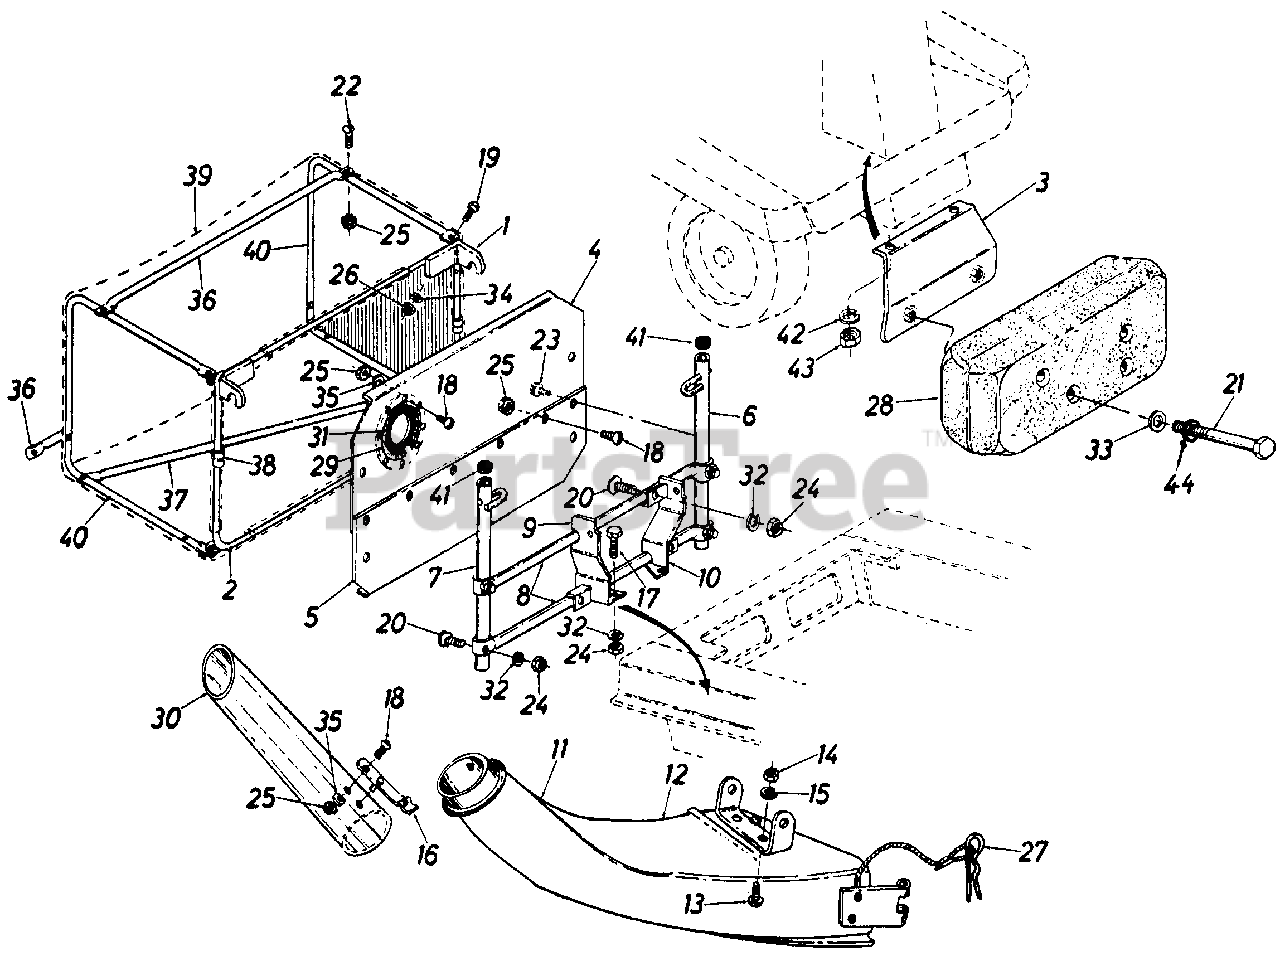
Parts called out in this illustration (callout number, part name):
1	Catcher Frame Ass'y. - Upper
2	Gatcher Frame Ass'y. - Lower
3	Counterweight Support 8racket. Ass'y.
4	Front Cover - Upper Half
5	Front Cover - Lower Half
6	L.H. Vertical Support Ass'y.
7	R.H. Vertical Support Ass'y.
8	Horizontal Support Tubing
9	Catcher Support B rkt. Ass'y.- R . H .
10	Catcher Support B rkt. Ass'y.- L. H .
11	Discharge Chute Ass'y.
12	Brkt. Chute Hinge
13	Carr. Bolt 1/4-20 x .62" Lg.
14	Hex Nut 1/4-20 Thd.*
15	L-Wash. 1/4" I.D.*
16	Spring Lock Ass'y.
17	Hex Bolt 5/16-18 x .75" Lg. *
18	Truss Mach. Scr. #10-24 x .38" Lg. *
19	Hex Bolt 1/4-20 x .62" Lg.*
20	Curved Calr. Boil 5/16-18 x 1.75" Lg.
21	Hex Bolt 3/8-16 x 4.50" Lg.*
22	Truss Mach. Scr. #10-24 x 1.0" Lg. *
23	Hex Wash. Hd. AB-Tap Scr. 1/4" x.62" Lg.
24	Hex Nut 5/16-18 Thd.*
25	Hex Sems Nut #10-24 Thd.
26	Hex Nut 1/4-2 Thd.*
27	Internal Cotter Pin
28	Counter Weight - 38#
29	Trim Strip - 24"
30	Grass Chute Tube
31	Rubber Flap
32	L-Wash . 5/16" I.D. *
33	Flat Washer 3/8" I.D. x 1.25" O.D. x .17
34	L-Wash. 1/4" I.D.*
35	F l-Wash . . 203" I . D . x .41 " O.D. x .040
36	Grass Catcher Handle
37	Grass Catcher Handle
38	Tubing Connector 1/2" I.D.
39	Grass Bag
40	Catcher Side Frame
42	L-Wash. 5/16" I.D.*
43	Hex Nut 5/16-18 Thd.*
44	Bell-Wash. 3/8" I.D. x 7/8" O.D.
